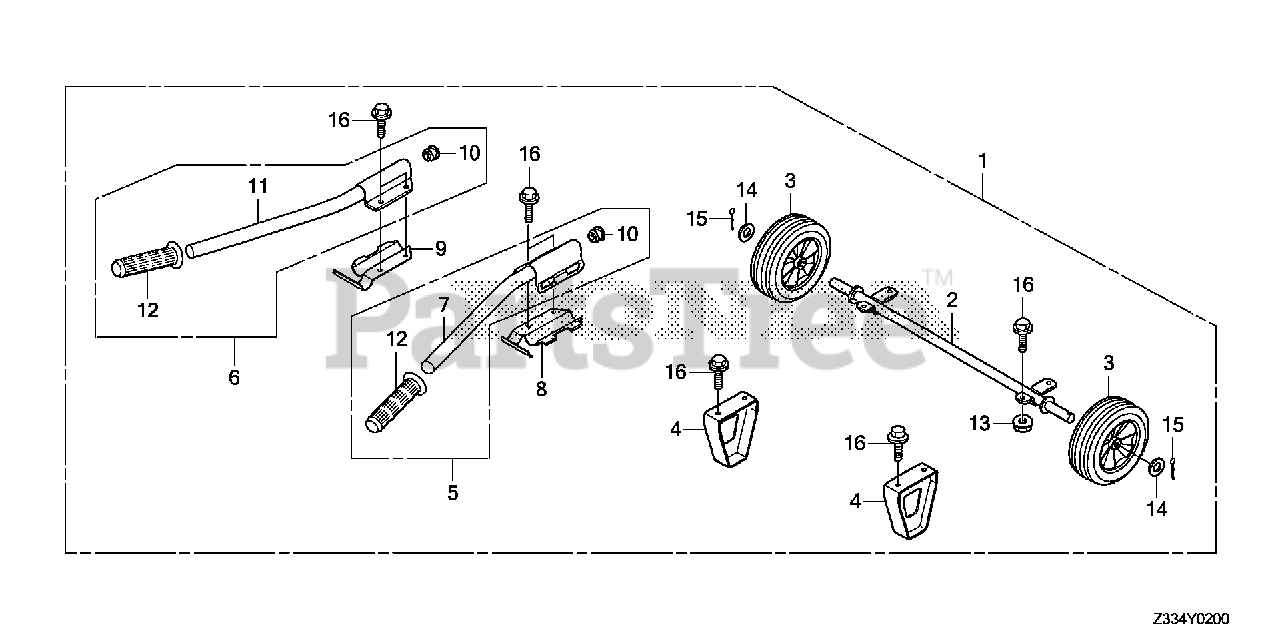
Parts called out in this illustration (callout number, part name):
1	WHEEL KIT (2-WHEELS) *NH105* (MAT BLACK)
2	SHAFT, WHEEL *NH105* (MAT BLACK)
3	WHEEL (254X63.5) (COO)(FOR U.S.A.)
4	STAND *NH105* (MAT BLACK)
5	HANDLE ASSY., R. (UPPER) *NH105* (MAT BLACK)
6	HANDLE ASSY., L. (UPPER) *NH105* (MAT BLACK)
7	HANDLE, R. (UPPER) *NH105* (MAT BLACK)
8	BRACKET, R. HANDLE (LOWER) *NH105* (MAT BLACK)
9	BRACKET, L. HANDLE (LOWER) *NH105* (MAT BLACK)
10	CAP, HANDLE (LOWER)
11	HANDLE, L. (UPPER) *NH105* (MAT BLACK)
12	GRIP, HANDLE
13	NUT, FLANGE (8MM)
14	WASHER, PLAIN (20MM)
15	PIN, SPLIT (4.0X28)
15	PIN, SPLIT (4.0X30)
16	BOLT, FLANGE (8X16)
